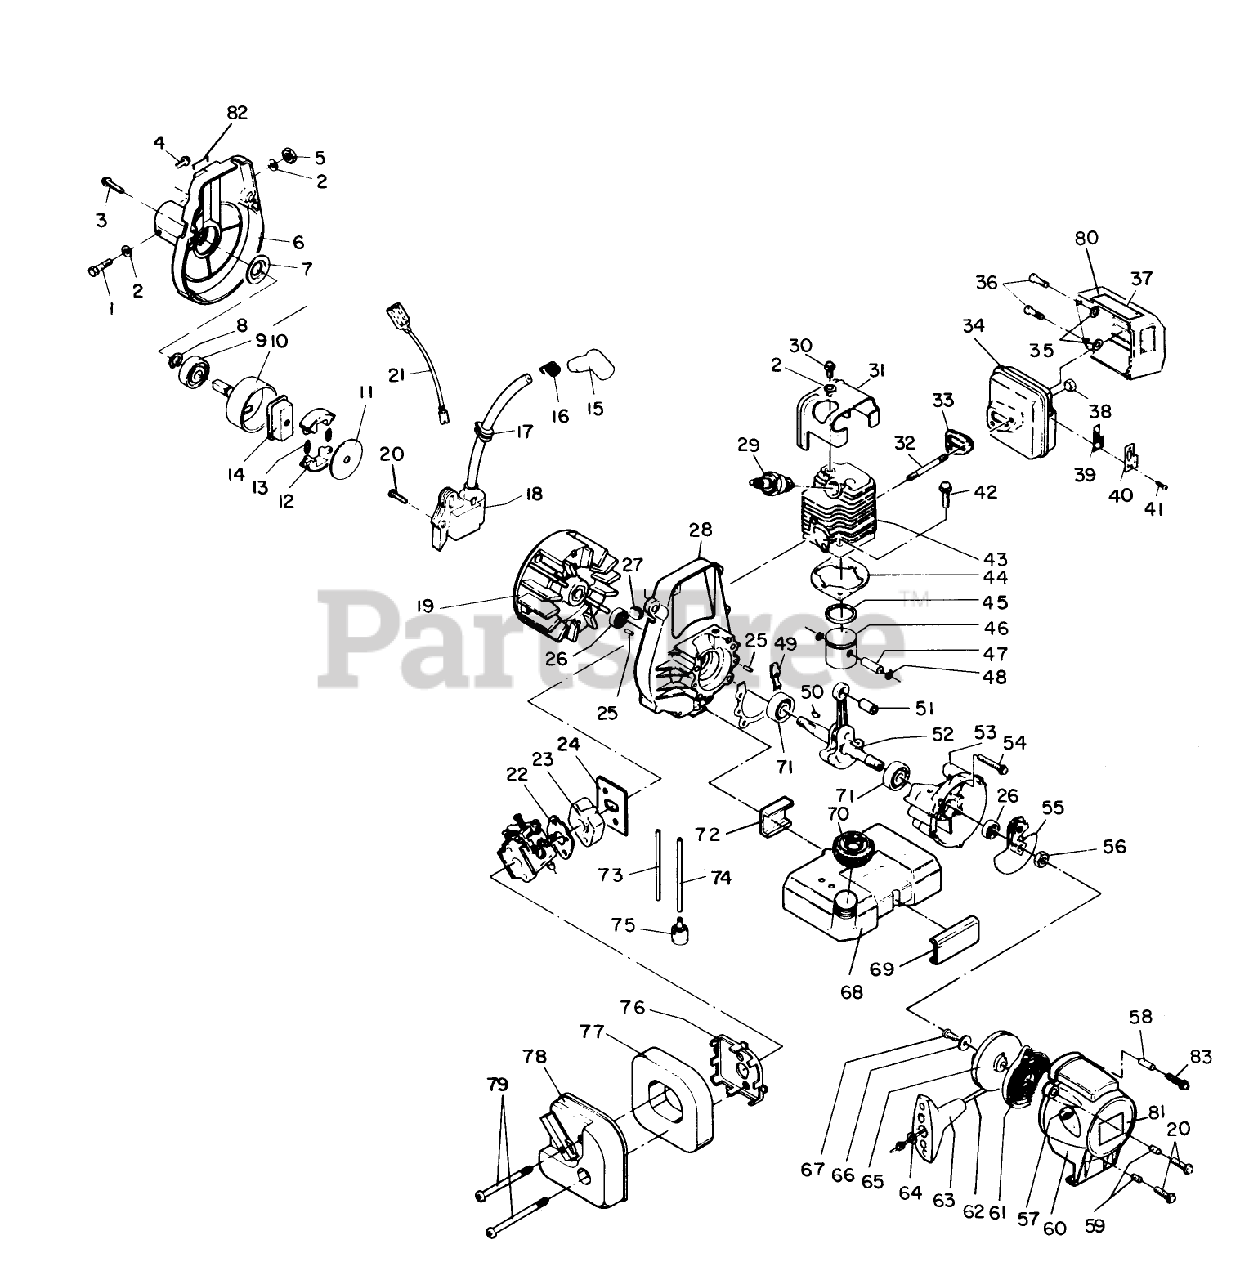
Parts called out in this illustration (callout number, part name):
57	ORDER MCCUL #218932
80	DECAL-SURFACE, HOT
81	DECAL
82	DECAL-SURFACE, HOT
